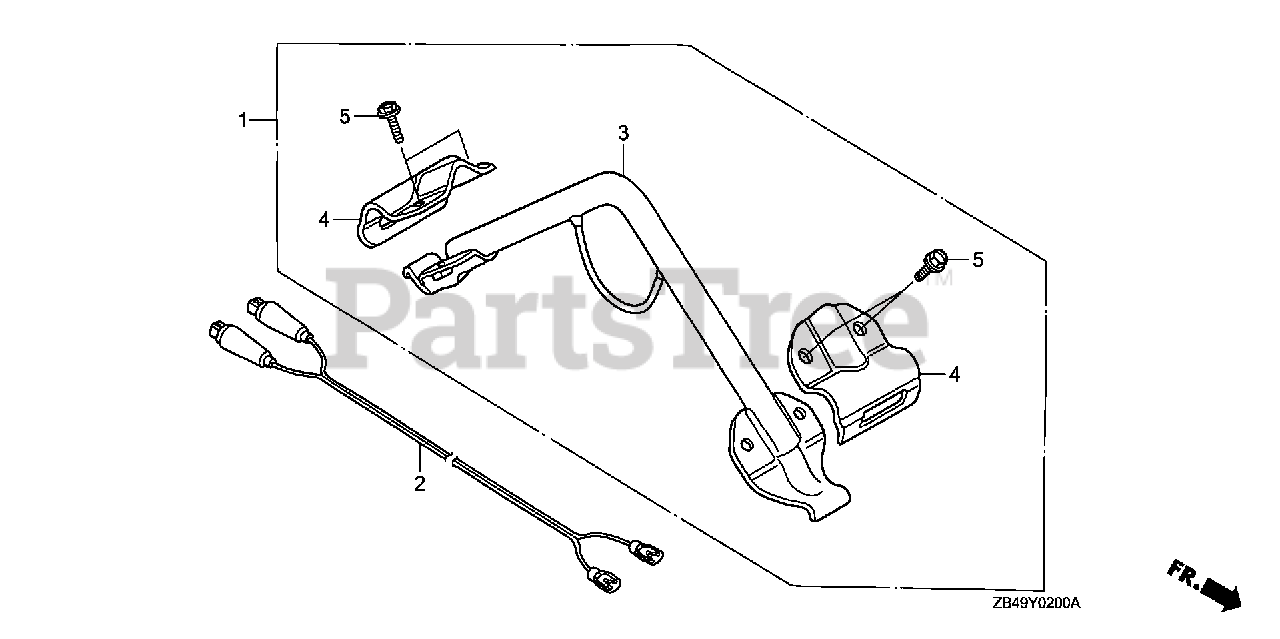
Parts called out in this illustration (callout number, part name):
1	HANGER KIT
3	HANGER
4	BRACKET, HANGER (UPPER)
5	BOLT, FLANGE (8X16)
